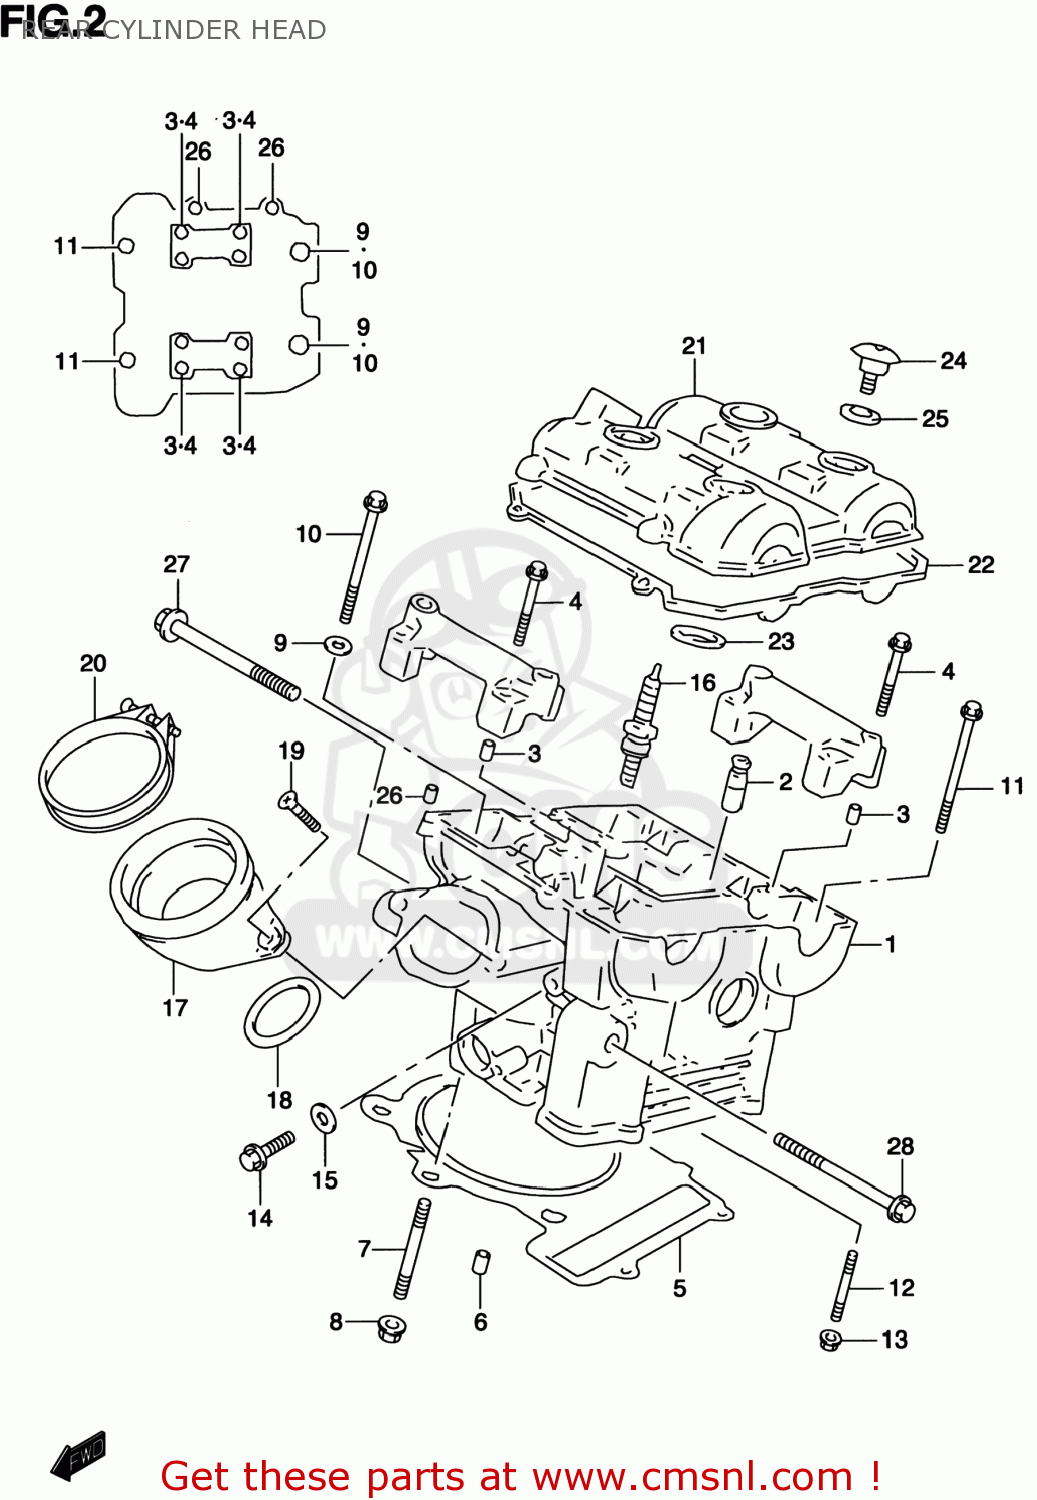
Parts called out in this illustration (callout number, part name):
1	HEAD ASSEMBLY,CYLINDER
2	GUIDE,VALVE
3	PIN(6.2X8X11)
4	BOLT(6X39)
5	GASKET,CYLINDER HEAD (NAS)
6	PIN
7	BOLT,STUD
8	NUT
9	WASHER(10.5X19X2)
10	BOLT(10X175)
11	BOLT(6X70)
12	BOLT,STUD
13	NUT
14	BOLT
15	GASKET(5.8X13X1.2) (NAS)
16	PLUG,SPARK(CR9EK)
17	PIPE ASSY,INTAKE
18	O RING(D:2.4,ID:55.6)
19	SCREW
20	CLAMP
21	COVER,CYLINDER HEAD RR
22	GASKET,CYL HEAD COVER NO.1 (NAS)
23	GASKET,CYL HEAD COVER NO.2
24	BOLT(7X17.5)
25	WASHER(10.6X25.5X2.3)
26	PIN(6.2X8X11)
27	BOLT
28	BOLT
